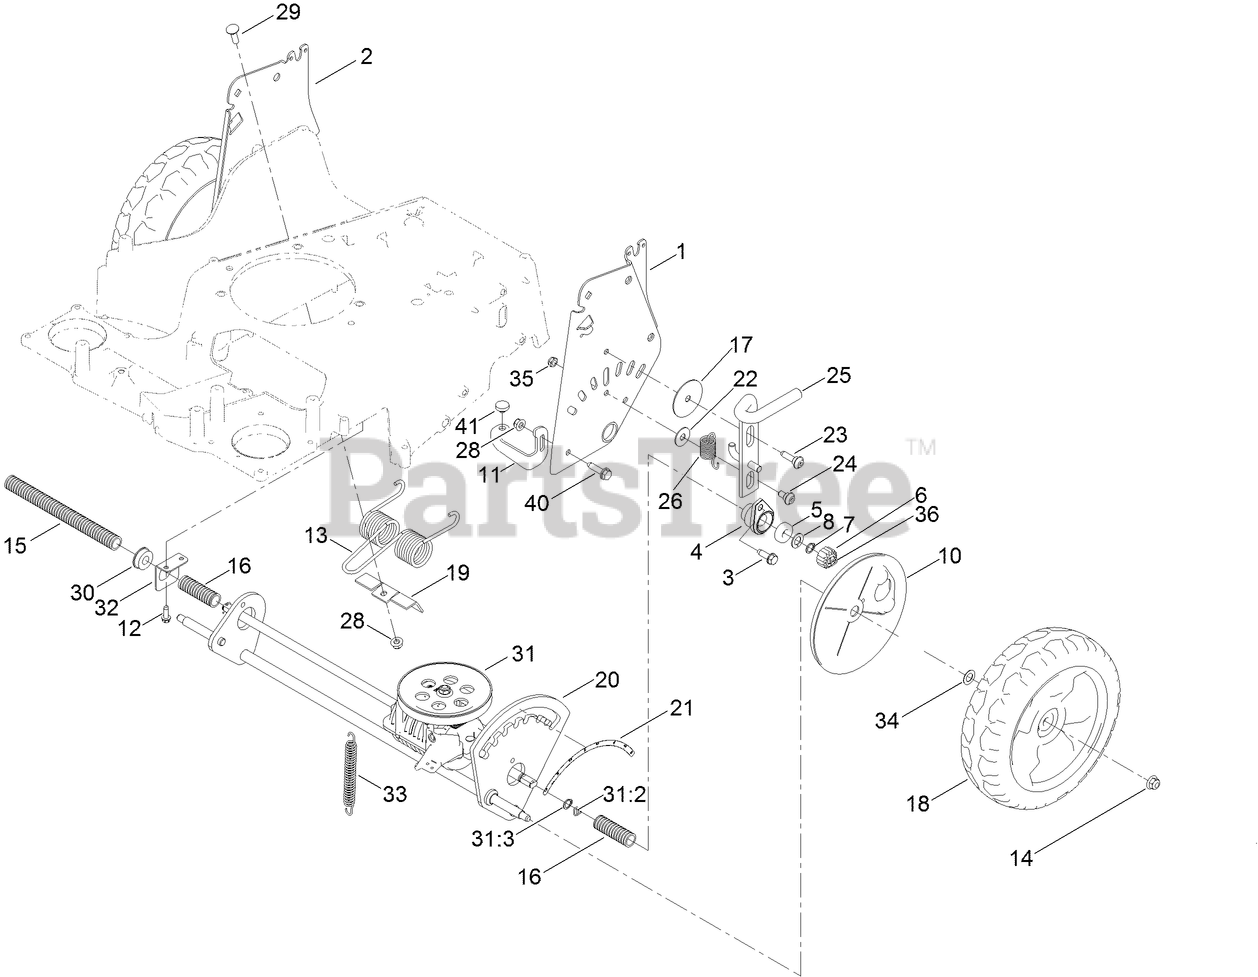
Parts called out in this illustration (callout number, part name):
1	LH HOC PLATE ASM
2	RH HOC PLATE ASM
3	SCREW-THD ROLL, HWH
4	RETAINER-BEARING
5	BEARING-BALL
6	GEAR-PINION, 15T
7	RING-RETAINING
8	WASHER-THRUST
10	COVER-GEAR
11	BRACKET-STOP, ADJUSTABLE
12	SCREW-HWHTF
13	SPRING-TORSION
14	NUT-HF, NI
15	CONDUIT-CONVOLUTED
16	CONDUIT-CONVOLUTED
17	WASHER-PLAIN
18	10.5 INCH WHEEL ASM
19	BRACKET
20	AXLE-REAR
21	DECAL-HOC, REAR
22	WASHER
23	SCREW-SHOULDER, BHTF
24	BOLT-SHOULDER
25	LOCK-HEIGHT, ADJUST
26	SPRING-EXTENSION
28	NUT-HF, NI
29	BOLT-CARR
30	BEARING-BALL
31	TRANSMISSION KIT
31:2	PIN-SNAP
31:3	RING-RETAINING
32	MOUNT-BEARING
33	SPRING-EXTENSION
34	WASHER-PLAIN
35	NUT-LOCK, NI
36	PIN-SNAP
40	SCREW-HWHTF
41	BUMPER
